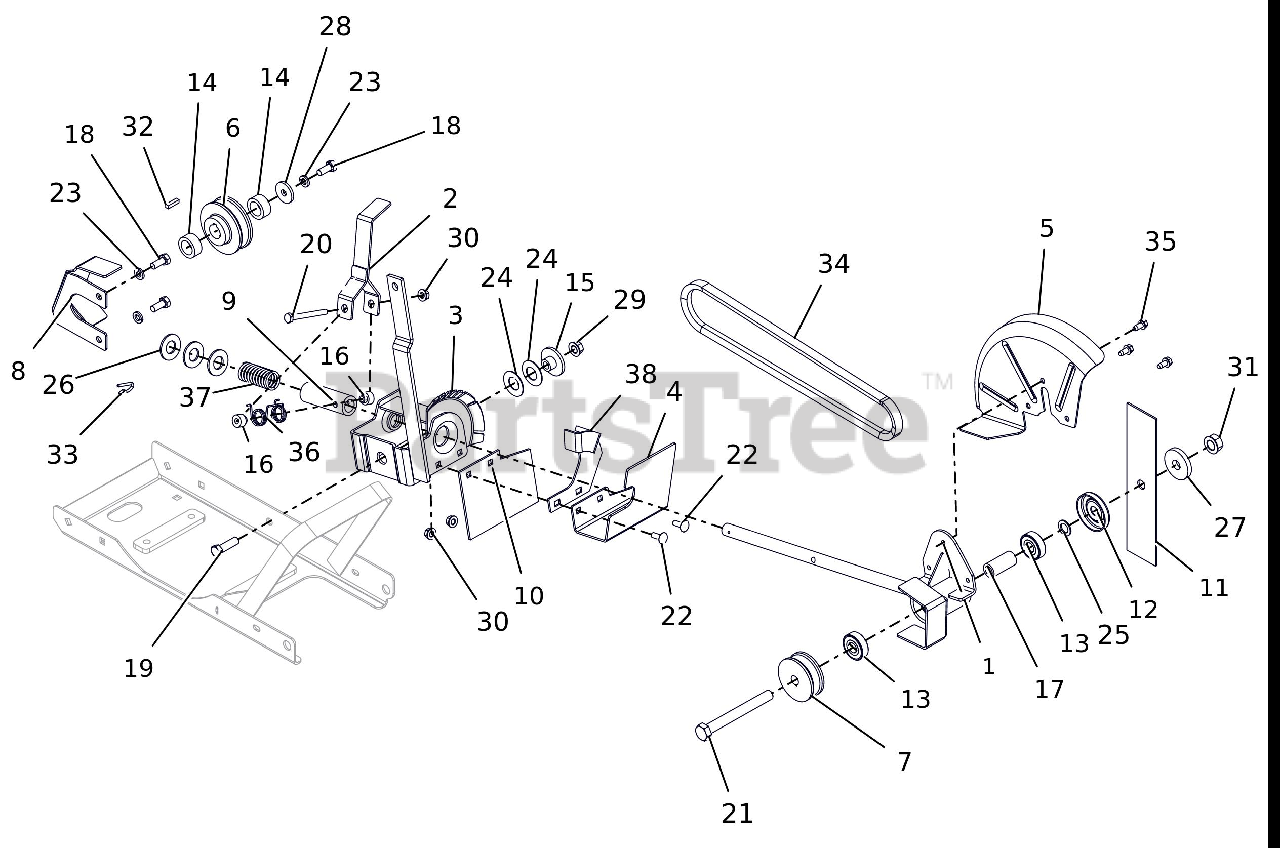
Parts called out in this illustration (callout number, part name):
1	SPINDLE,CUTTER HEAD
2	LEVER,TILT
3	MOUNT,CUTTER HEAD PIVOT
4	KIT-GUARD
5	GUARD,BLADE
6	PULLEY, ENGINE
7	PULLEY, BLADE
8	KIT-ENGINE BELT FINGER
9	COLLAR, SPRG
10	FLAP, RUBBER
11	BLADE, EDGER-9"
12	SLINGER, BEARING
13	BRG-BALL .500X1.38X.437
14	BSHG-SLV .766 X 1.125 X .500
15	BSHG,FLG .384X.635X.41X1.49
16	BSHG,FLG .263X.393X.18X.625
17	BSHG-SLV .500X.750X1.560
18	BLT-HEX .31-24X.75 YWZC GR5
19	@BLT-HEX .38-16X1.25 GR5 YWZC
20	@BLT-HEX .25-20X2.50 GR5 YWZC
21	@BLT-HEX .50-13X4.50 GR5 YWZC
22	@BLT-RDHDSQNK .25-20X.75 G5YZ
23	WSHR-LK .312X.097 HVY YWZC
24	WASHER, BELLEVILLE
25	WSHR-FL-STL .52X.827X.062 YWZC
26	@WSHR-FL-STL.656X1.31X.095 YWZ
27	WSHR-FL-STL .515X1.625X.250 YZ
28	WSHR-FL-STL .344X1.125X.135
29	@NUT-LK-TOP-FLG .38-16 YWZC
30	@NUT-LK-TOP-FLG .25-20 YWZC
31	@NUT-LK-TOP-FLG .50-13 YWZC
32	KEY-SQ .188X.75X.188
33	PIN, SPRING CLIP
34	V-BELT, 4L-WRAPPED
35	SCR-TAP .25-20X.50 HWH TR YWZ
36	SPRING, TORSION
37	SPRING, COMPRESSION
38	BRACKET,LIMIT
